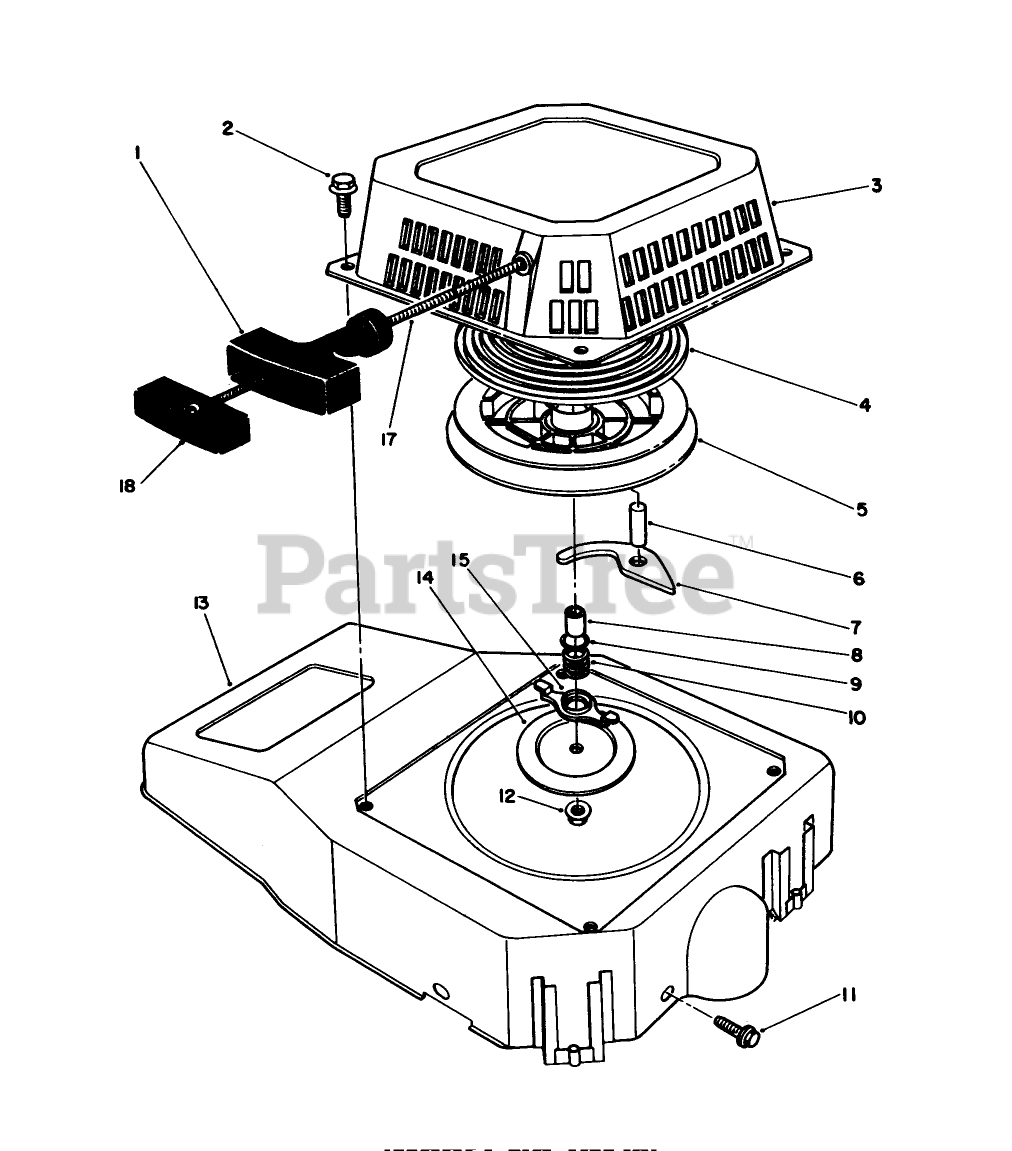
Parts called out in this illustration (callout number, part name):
1	HANDLE
2	SCREW-HHF
4	SPRING
9	WASHER
13	SHROUD
